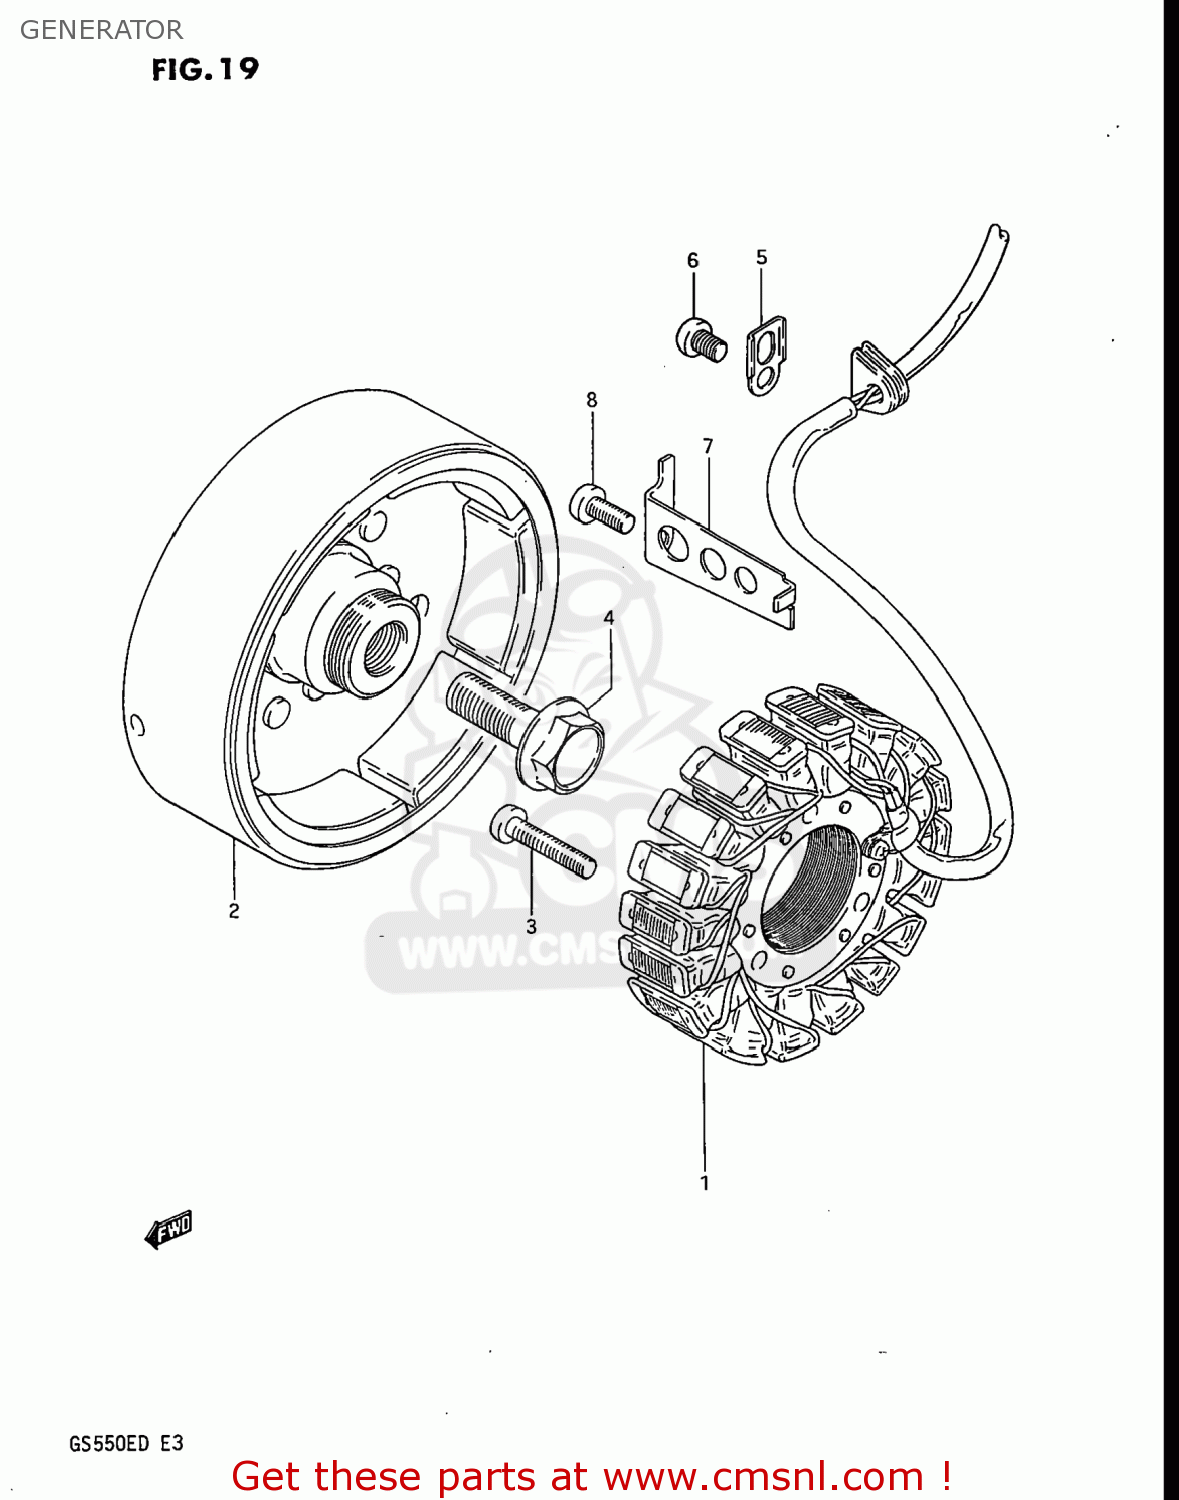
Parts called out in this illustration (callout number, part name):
1	STARTER ASSY
2	ROTOR ASSEMBLY
3	SCREW 6X30
4	BOLT(14X43)
5	CLAMP,GENERATOR LEAD WIRE
6	SCREW
7	CLAMP,GENERATOR LEAD WIRE
8	SCREW
